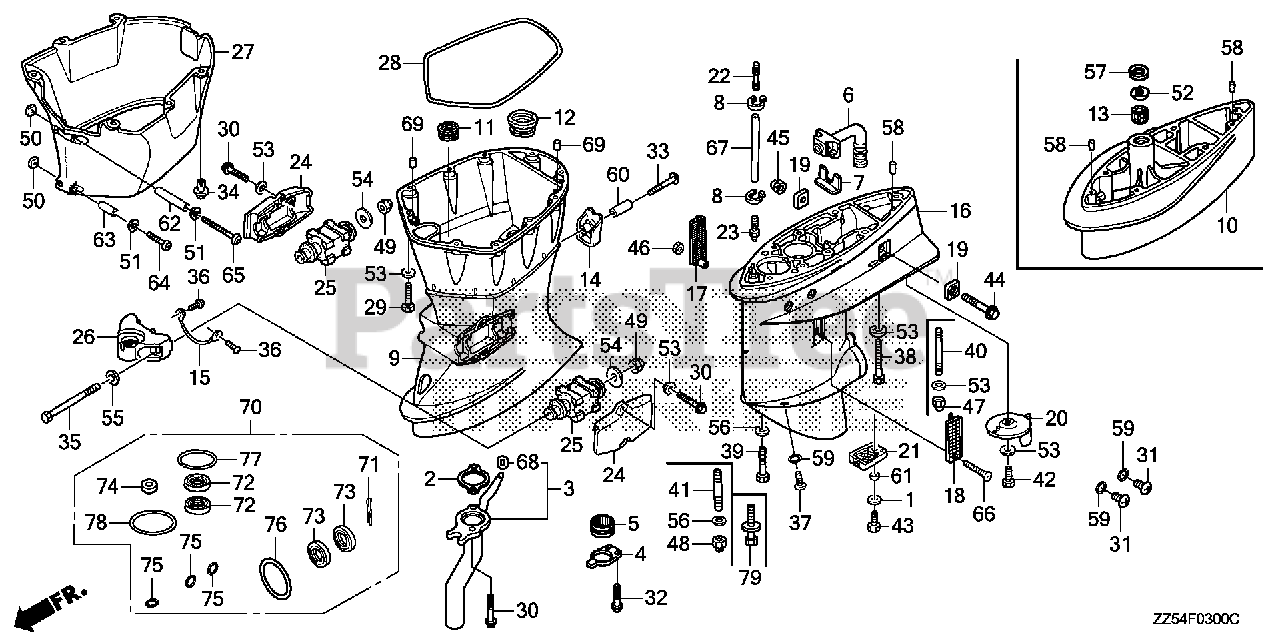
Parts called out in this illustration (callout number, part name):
1	WASHER, PIVOT
2	GASKET, EX. PIPE
3	PIPE KIT, EX.
4	HOLDER, EX. PIPE GROMMET
5	GROMMET, EX. PIPE
6	TUBE, WATER (LOWER)
7	PLATE, RUBBER SETTING
8	BAND, WIRE
9	CASE, EXTENSION *NH282MU* (OYSTER SILVER METALLIC-U)
11	GROMMET, EXTENSION CASE
12	RUBBER, DRAIN PLUG
14	COVER, DRAIN PLUG *NH282MU* (OYSTER SILVER METALLIC-U)
15	WIRE, LEAD (1.5X116MM)
16	CASE, GEAR *NH282MU* (OYSTER SILVER METALLIC-U)
17	SCREEN, R. WATER
18	SCREEN, L. WATER
19	METAL, ANODE
20	TAB, TRIM *NH282MU* (OYSTER SILVER METALLIC-U)
21	SCREEN, WATER (LOWER)
22	END, NIPPLE
23	NIPPLE, SENSOR
24	HOUSING, R. MOUNTING (LOWER) *NH282MU* (OYSTER SILVER METALLIC-U)
25	RUBBER, SETTING (LOWER)
26	HOUSING, CENTER MOUNTING (LOWER) *NH282MU* (OYSTER SILVER METALLIC-U)
27	COVER (LOWER) *NH282MU* (OYSTER SILVER METALLIC-U)
28	RUBBER, COVER (LOWER)
29	BOLT, HEX. (8X35) Use up to Frame SN 4800712.
30	BOLT, FLANGE (8X25)
31	BOLT, OIL CHECK
32	BOLT, FLANGE (6X20) (ENGINE NO.)
33	SCREW, SPECIAL (6X35)
34	SCREW, RIVET (8X15)
35	BOLT, HEX. (12X162)
36	SCREW, PAN (6X8)
37	BOLT, DRAIN PLUG
38	BOLT, HEX. (8X65)
39	BOLT, HEX. (10X40)
42	BOLT, HEX. (8X20)
43	BOLT, HEX. (6X16)
44	BOLT, FLANGE (6X25)
45	NUT, SELF-LOCK (6MM)
46	NUT, SELF-LOCK (5MM)
49	NUT, SELF-LOCK (12MM)
50	NUT, PLATE (5MM)
51	WASHER, PLAIN (5MM)
53	WASHER, PLAIN (8MM) Use up to Frame SN 4800712.
54	WASHER, PLAIN (12MM)
55	WASHER, PLAIN (12MM)
56	WASHER, PLAIN (10MM)
58	PIN, DOWEL (6X10)
59	O-RING (6.9X1.45)
60	COLLAR, DISTANCE (6X10.5X25)
61	COLLAR, WATER SCREEN (LOWER)
62	COLLAR, DISTANCE (5X7X38)
63	COLLAR, DISTANCE (5X7X23)
64	SCREW, PAN (5X30)
65	SCREW, PAN (5X45)
66	SCREW, OVAL (5X40)
67	BULK HOSE, VACUUM (5X3000) (5X250)
68	GROMMET, EX. BREATHER PIPE
69	PIN, DOWEL (6X15)
69	PIN, DOWEL (6X10)
70	CASE KIT, GEAR
71	PIN, COTTER (4.0)
72	SEAL, WATER (17X30X7)
73	SEAL, WATER (22X35X7)
74	SEAL, WATER (7MM)
75	O-RING (6.9X1.45)
76	O-RING (69X3.1)
77	O-RING (41.7X3.5)
78	O-RING (47X3.1)
79	BOLT-WASHER (10X40)
